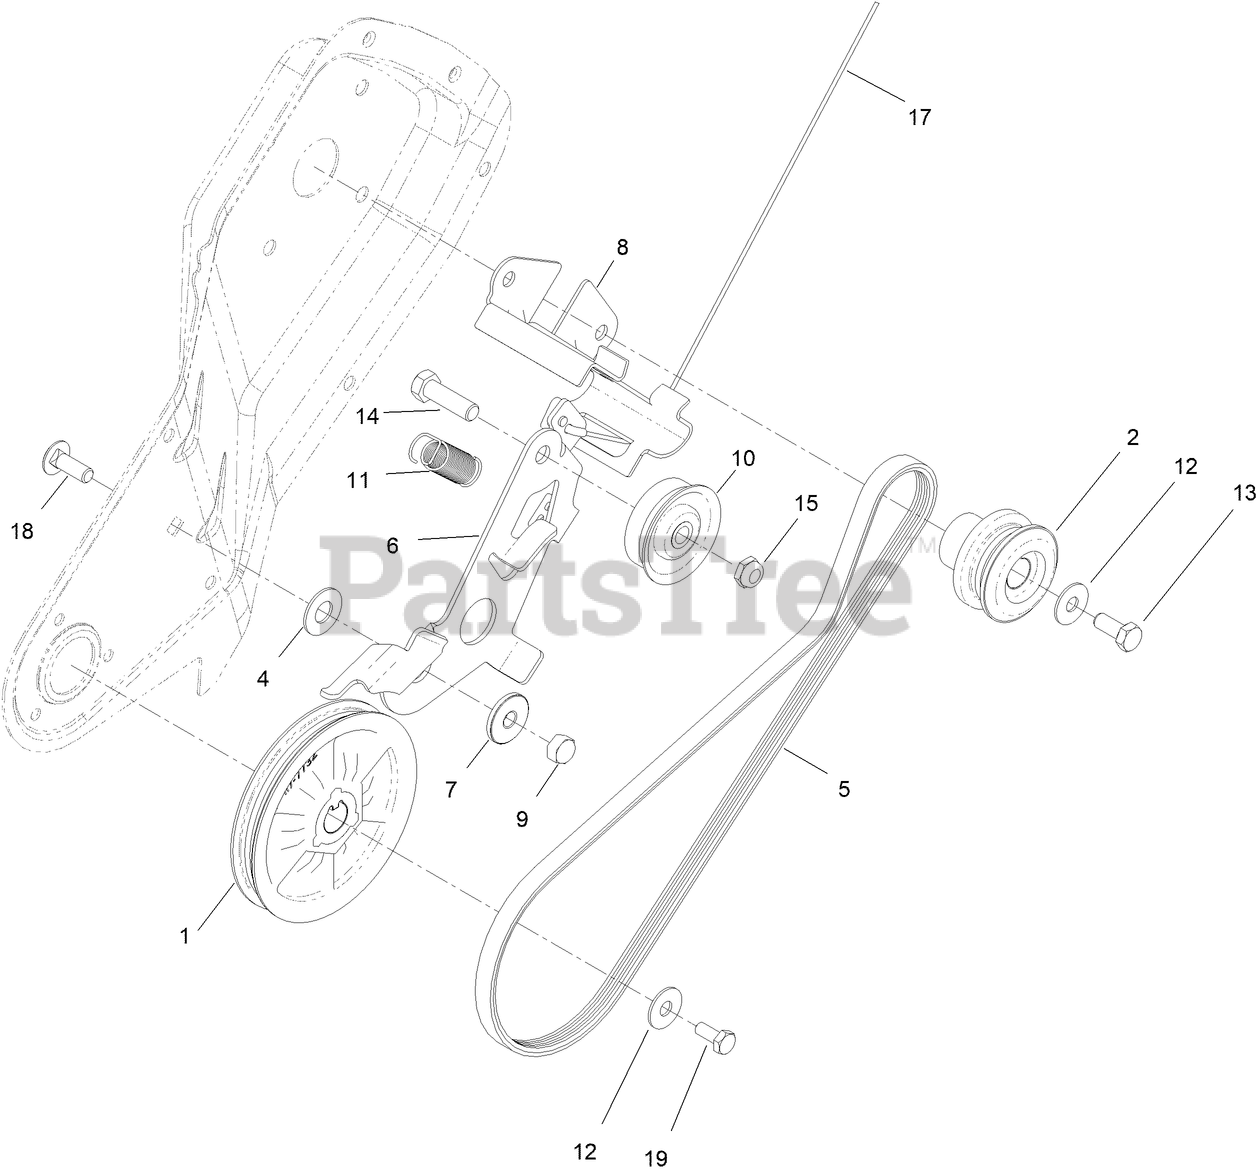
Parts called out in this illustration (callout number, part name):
1	ROTOR PULLEY ASM
2	PULLEY-ENGINE
4	WASHER
5	BELT-V, RIBBED
6	ARM-IDLER
7	BUSHING-IDLER
8	GUIDE-BELT
9	NUT-HEX
10	PULLEY-IDLER
11	SPRING-BRAKE
12	WASHER-BELLEVILLE
13	SCREW-HH LOCK
14	SCREW-HH
15	NUT-HEX
17	CABLE-CLUTCH
18	BOLT-CARR
19	SCREW-HH LOCK
